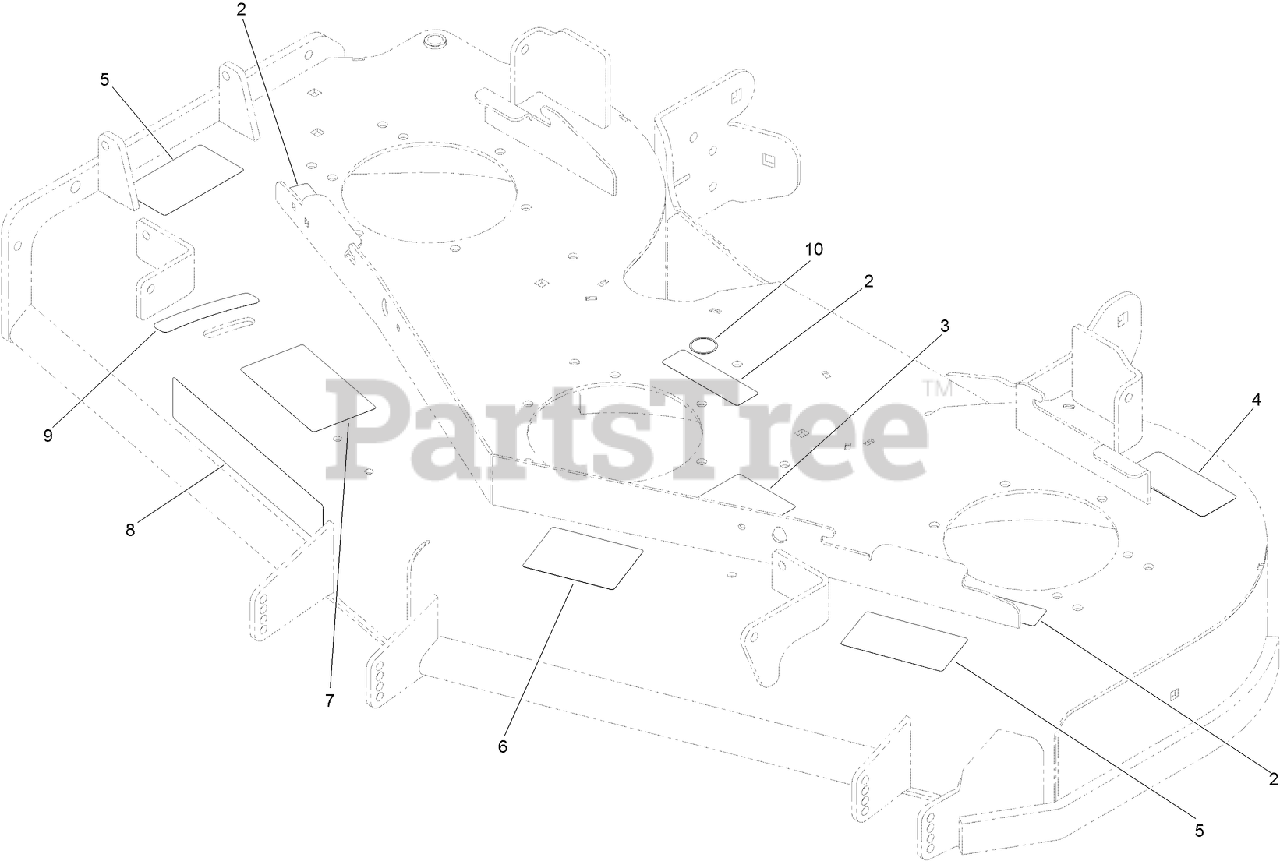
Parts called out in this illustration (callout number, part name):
2	DECAL-MISSING, COVER
3	DECAL-ROUTING, DECK BELT
4	DECAL-TORQUE, BLADE BOLT
5	DECAL-DANGER
6	DECAL-SCALP, ANTI
7	DECAL-ADJUSTMENT, BAFFLE
9	DECAL-SETTING, BAFFLE
10	DECAL-GREASE
